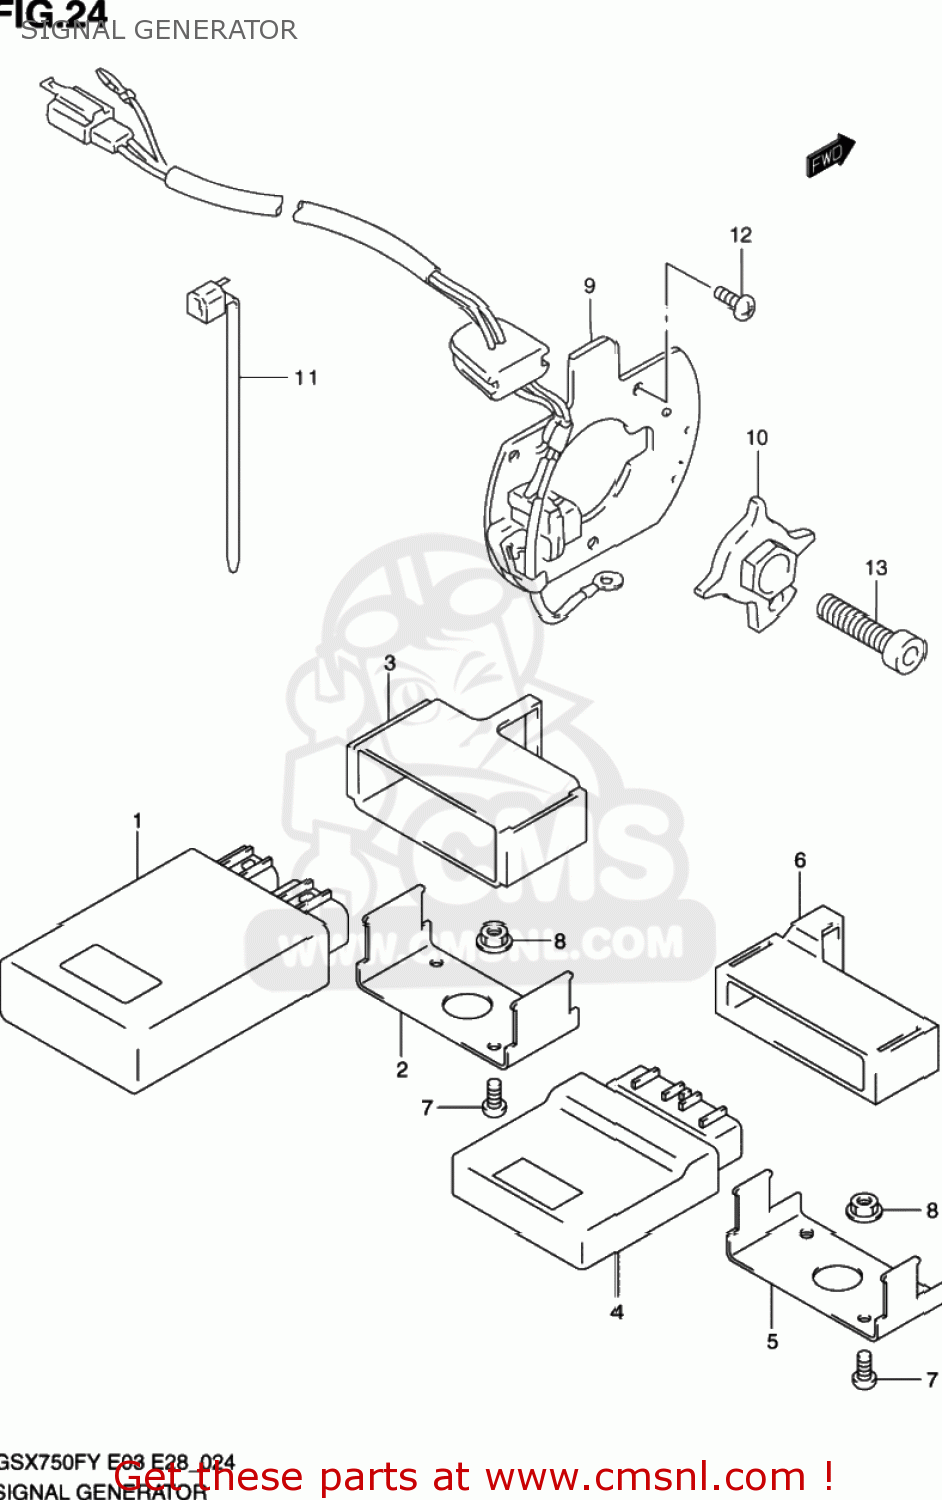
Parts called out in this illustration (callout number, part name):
1	IGNITOR ASSY
2	BRACKET,IGNITOR
3	CUSHION,IGNITOR
4	IGNITOR ASSY
5	BRACKET,IGNITOR
6	COVER,IGNITOR
7	SCREW 5X12
8	NUT
9	GENERATOR ASSY,SIGNAL
10	ROTOR,SIGNAL GENERATOR
11	CLAMP(L:125)
12	SCREW
13	BOLT
